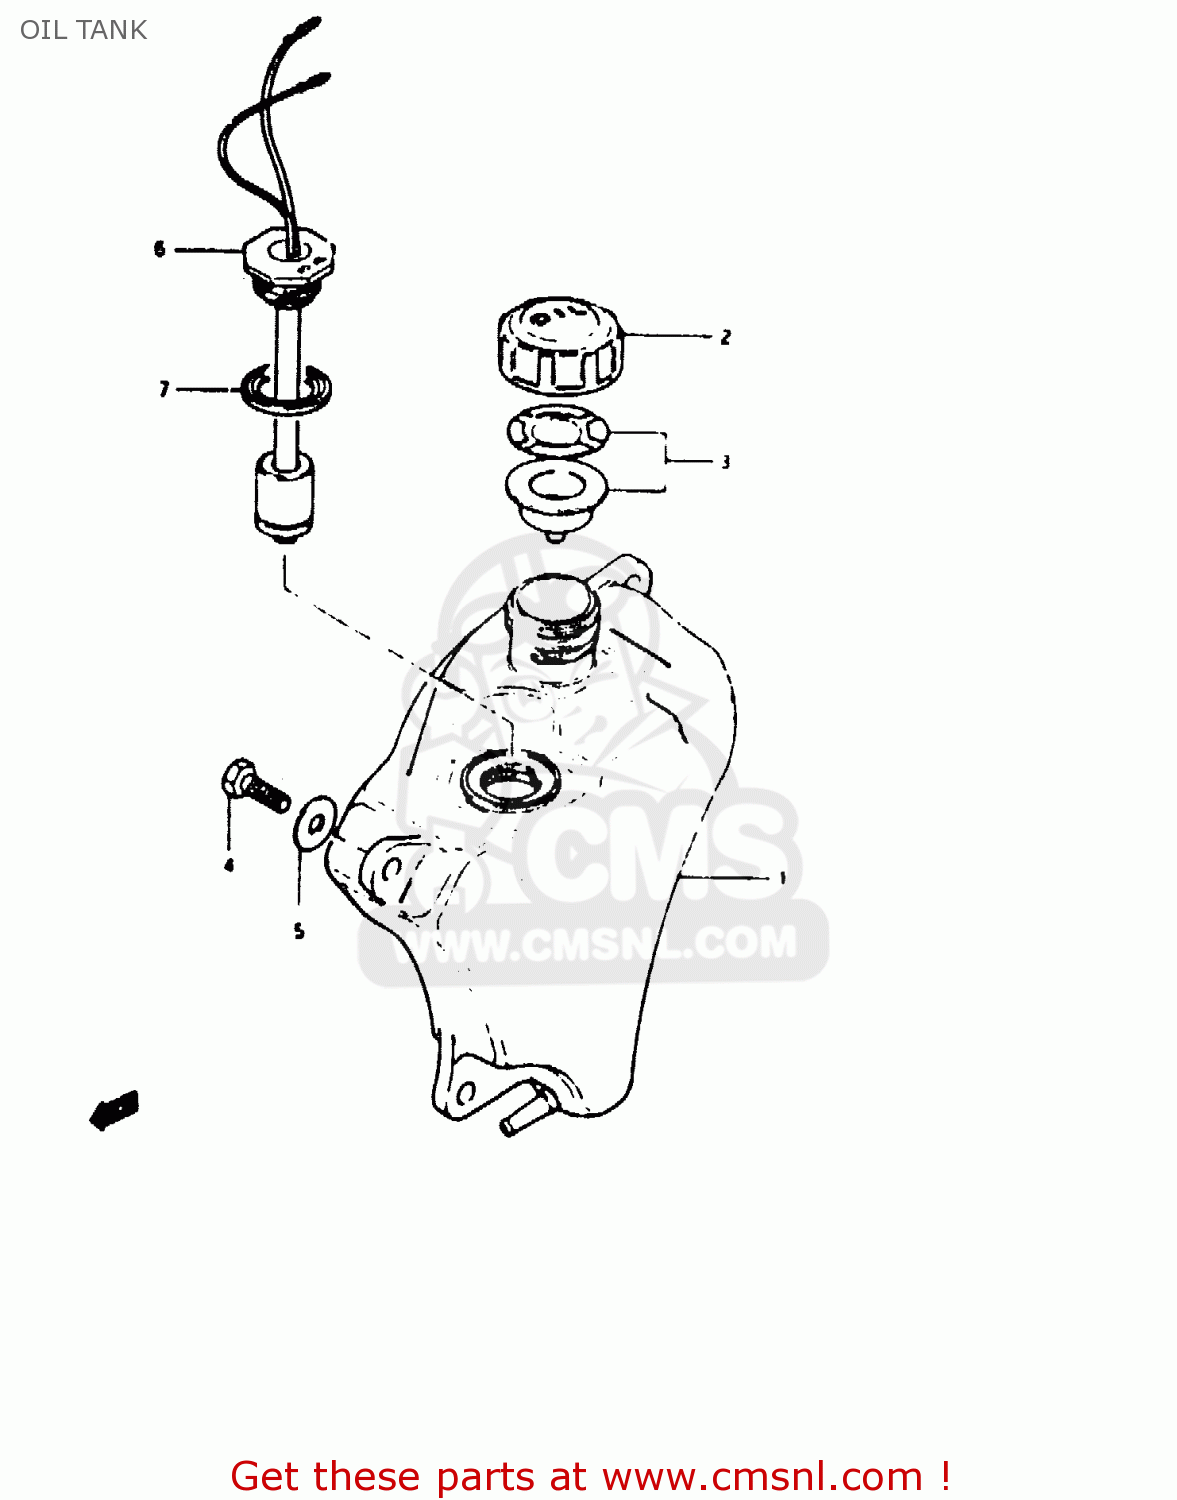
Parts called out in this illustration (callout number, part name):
1	TANK, OIL
2	CAP,OIL TANK
3	GASKET SET (NAS)
4	BOLT, UPPER
5	WASHER
6	SWITCH, OIL LEVEL
7	GASKET (NAS)
